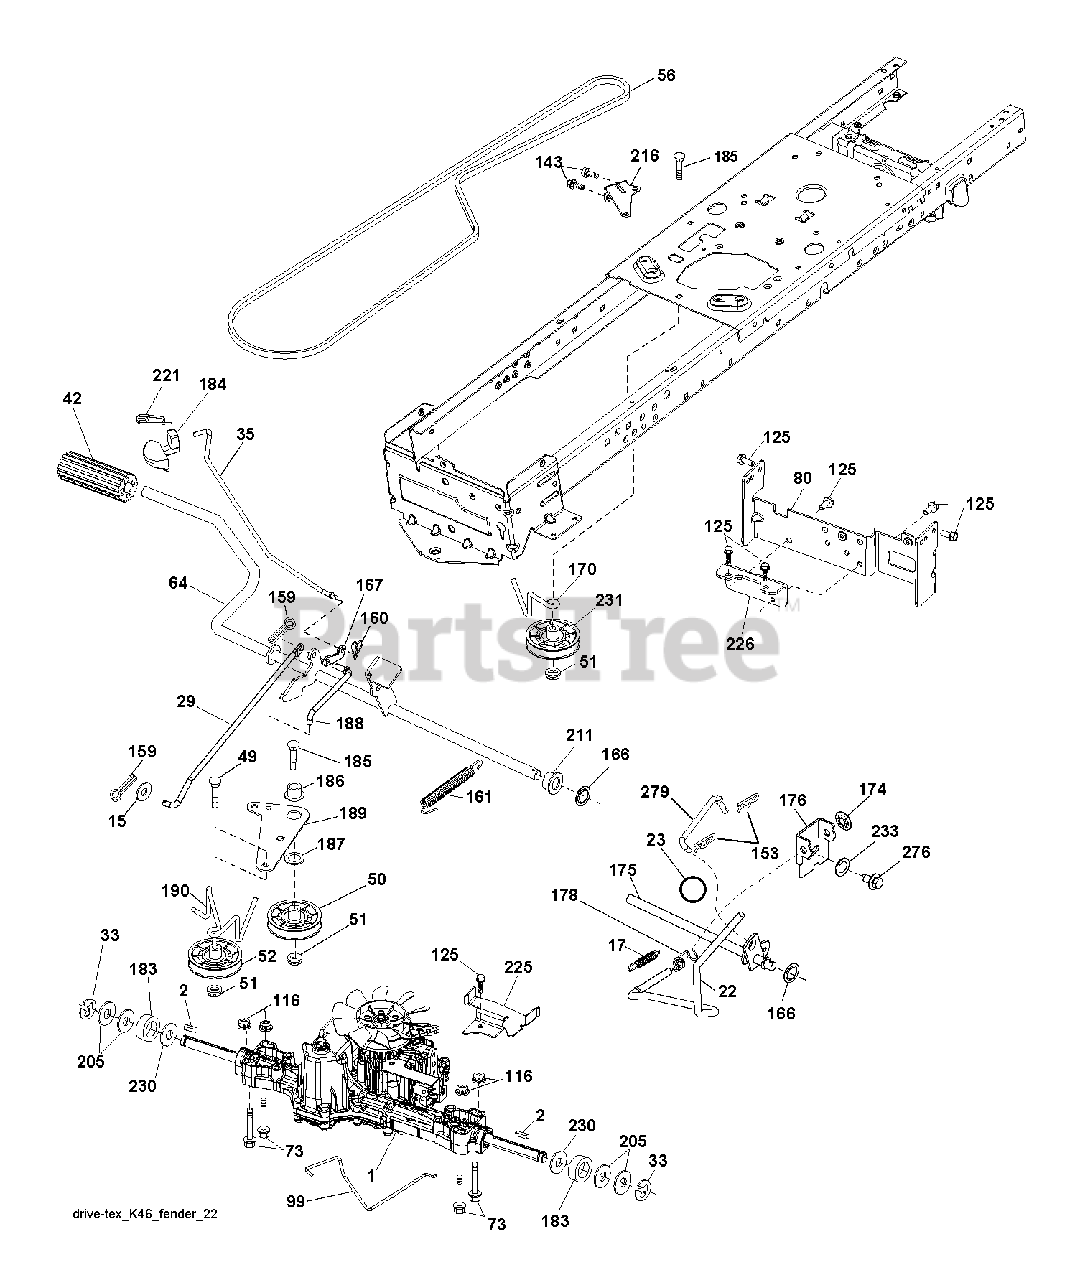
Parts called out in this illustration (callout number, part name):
2	SQUARE KEY
15	WASHER
17	SPRING.BRAKE.K46.GREEN
23	KNOB.DUCKHEAD.1/2
29	ROD.BRAKE.K46
35	ROD.CNTRL.PARK.PREDATOR.LT.TEX
42	PEDAL COVER T
50	IDLER.FLAT.910.OFFSET
51	NUT LOCK FLG 3/8-16 UNC
52	IDLER.V-GROOVE.910.OFFSET
56	V-BELT.MOWER.92.40.42/K46
64	SHAFT.ASM.PEDAL.BRAKE.
80	STRAP.TORQUE.K46.K57R.TT
99	ROD.SPRING.BYPASS.K46.LT.Z
116	NUT LOCK HEX FLANGE 5/16-18
125	SCREW
143	SCREW LT
153	RETAINER M
159	COTTER PIN
160	RETAINER CLIP
161	SPRING, RETURN LT
166	NUT.PUSH.625
167	LATCH.BRAKE.SPRING
170	KEEPER.CENTER SPAN.1.688
174	NUT.PUSH.500.2006
175	SHAFT.ASM.SHFT.T2.TLT
176	ARM.CLEVIS.ROD.SHIFT
178	SPRING.SHIFT.GT2006
183	SPACER AXLE
184	HANDLE.PARKING.BRK.PRED.LT.RED
186	SPACER.RETAINER
187	WASHER 12/32X2X10GA
188	RP LINK.CLUTCH.GROUND.DRIVE
189	BELLCRANK.GROUND.DRIVE.TEX.
190	KEEPER.BELLCRANK.DRIVE
211	BUSHING.SHAFT.BRAKE.HAND
216	BRACKET.PULLEY.IDLER.W/TEX
221	RETAINER.SPRING.CLIP.H
225	KEEPER.BELT.TRANSAXLE.K46
226	BRACKET.MOUNT.TORQUE.K46.TLT
230	WASHER.HARDENED
231	IDLER.V-GROOVE.1.688.OFFSET
233	WASHER SERRATED
276	BOLT FIN HEX 7/16-14 X 1
279	LINK.SHIFT.
